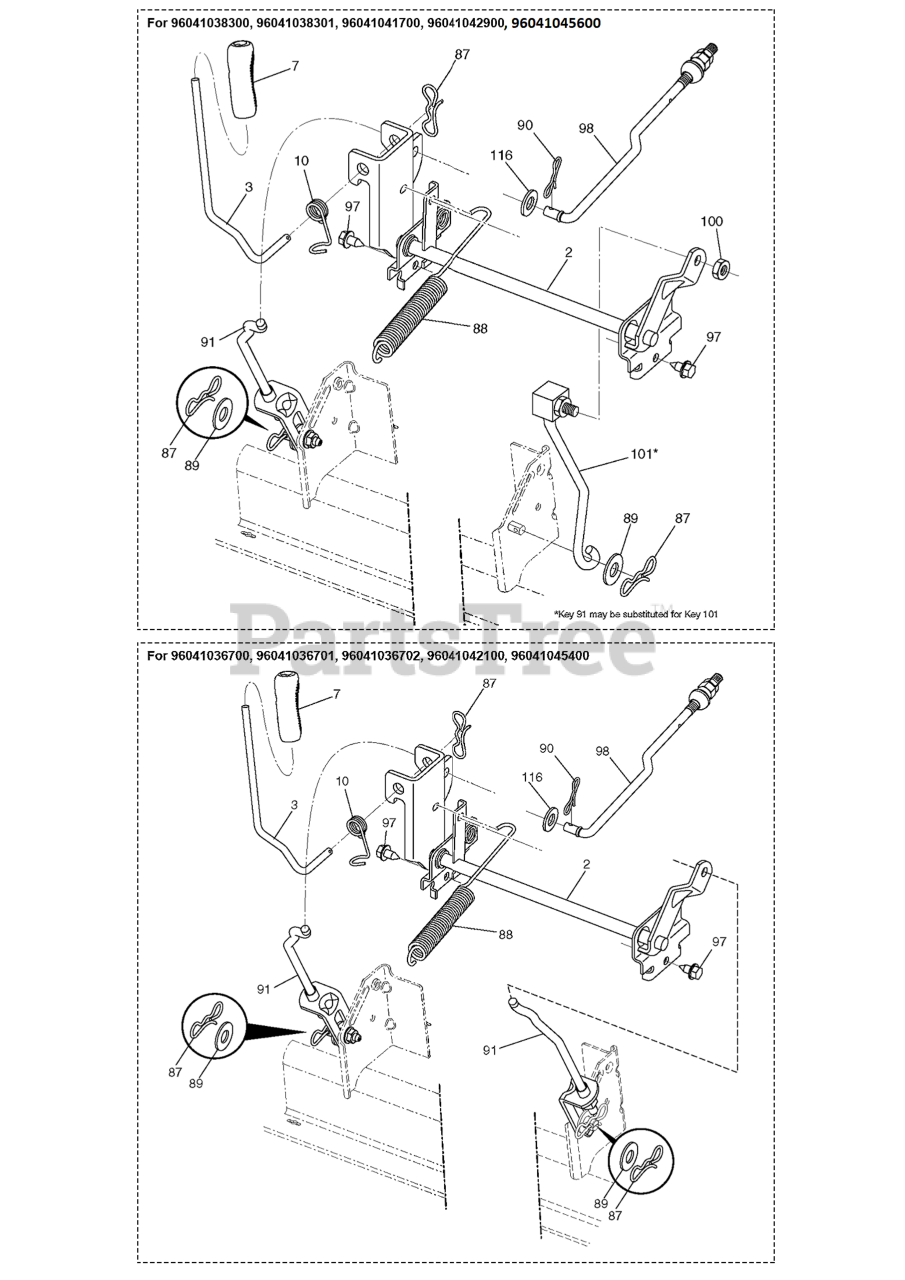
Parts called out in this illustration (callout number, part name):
2	SHAFT.ASM.CROSS.LIFT
7	GRIP.HANDLE.LIFT.PVC.BLACK
10	SPRING.TORSION.LIFT.HANDLE
87	PIN.COTTER.7/16.BOW TI.
88	SPRING.LIFT.ASSIST
89	WASHER.CLEAR.ZINC
90	PIN.COTTER.5/16.BOW TI
97	SCREW, 3/8-16X3/4
100	Nuts
101	LINK.ASM.LIFT.FIXE.38/42/46"
